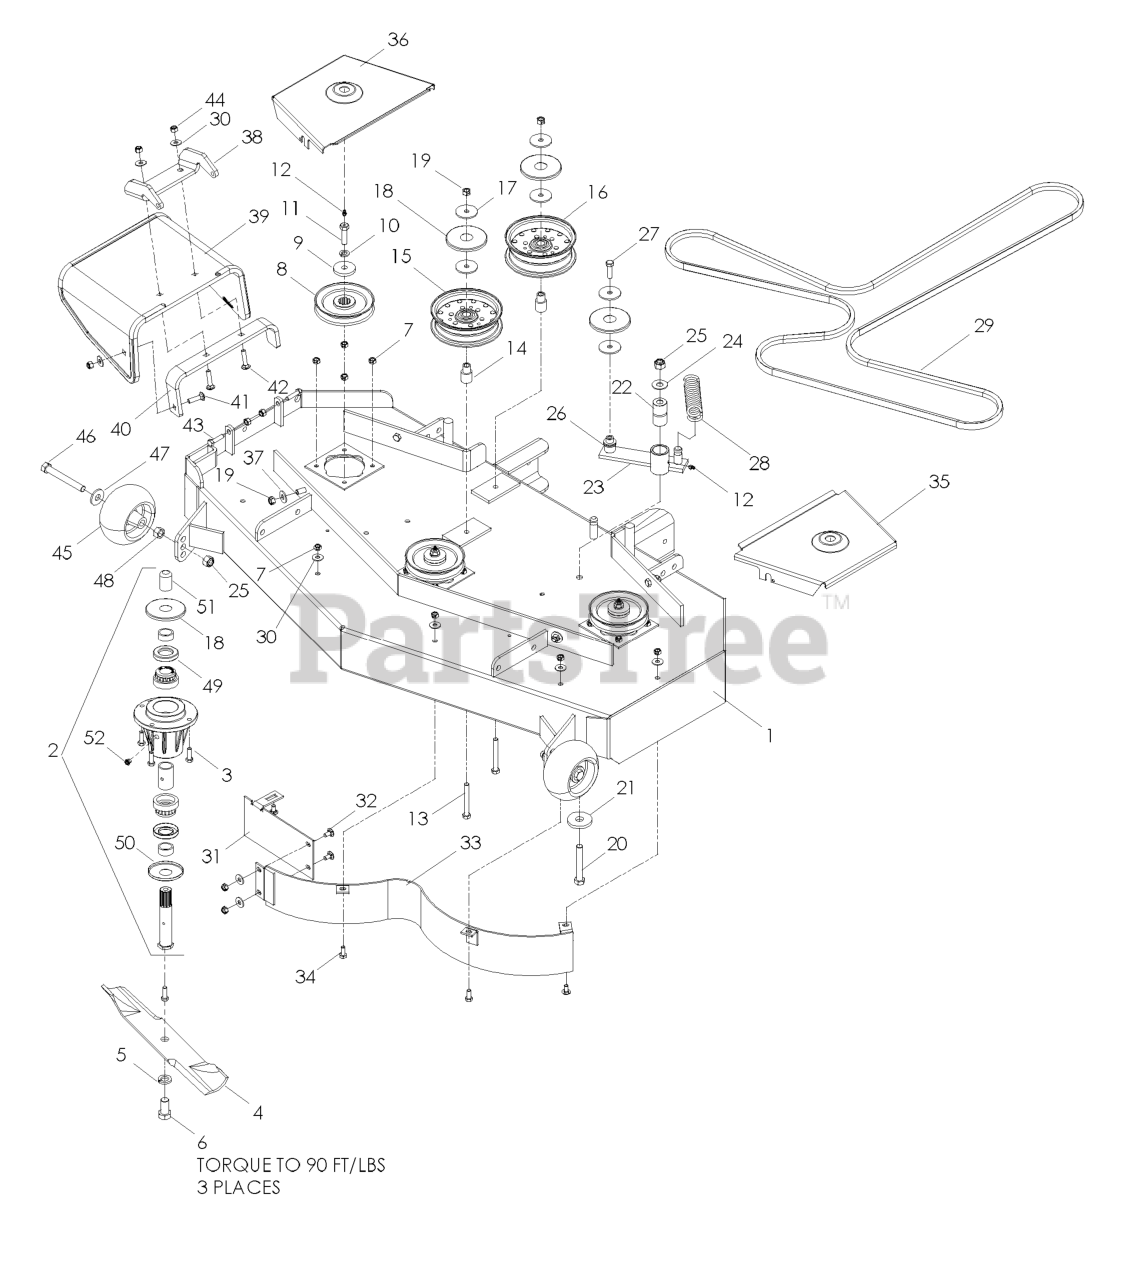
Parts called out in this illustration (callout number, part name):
1	DECK W/DECALS 48"
2	HOUSING ASM, 52/61
3	HCS 5/16C X 1
4	BLADE OEM 16 1/4"
5	LOCKWASHER 5/8
6	HCS 5/8F X 1 1/4
7	NUT 5/16C CENTERLOCK
8	PULLEY 42-48
9	SPINDLE WASHER
10	WASHER 7/16 LOCK
11	HCS 7/16-20 GD 8 SPEC
12	ZERK
13	HCS 3/8C X 3
14	IDLER BUSHING
15	IDLER PULLEY
16	IDLER PULLEY (TALL)
17	WASHER, 3/8 SPEC
18	TOP DUST CAP
19	NUT 3/8C CENTERBLOCK
20	HCS 1/2C X 3 1/4
21	WASHER, SUPPORT
22	PIVOT BUSHING
24	WASHER 1/2 FLAT
25	NUT 1/2-13 HEX NYLOC ZD
26	BUSHING
27	HCS 3/8C X 1 1/4 GR5
29	BELT, DECK
30	WASHER 5/16 FLAT
31	CENTER BAFFLE 48"
32	CARRIAGE BOLT 5/16C X 5/8"
33	MAIN BAFFLE - 48" DECK BLK
34	HCS 5/16C X 3/4
35	LT 48 SHIELD, ORG
36	RT 48 SHIELD, ORG
37	WASHER 3/8 FLAT
38	PIVOT BRACKET - CHUTE
39	CHUTE, RUBBER DISCHARGE WB
40	BRKT, REINF-CHUTE WB
41	BOLT, CARRIAGE 5/16X1-1/4
42	RHSNB 5/16-18 X 1-1/2 GR 5 ZD
43	HCS 5/16C X 1 1/4
44	NUT 5/16 NYLOC
45	GAUGE WHEEL
46	HCS 1/2-13 X 4 GR 5 ZD
47	WASH USS FLAT 1/2
48	NUT HEX 1/2
49	SHAFT SEAL
50	BOTTOM DUST CAP
52	PLUG-VENTED
